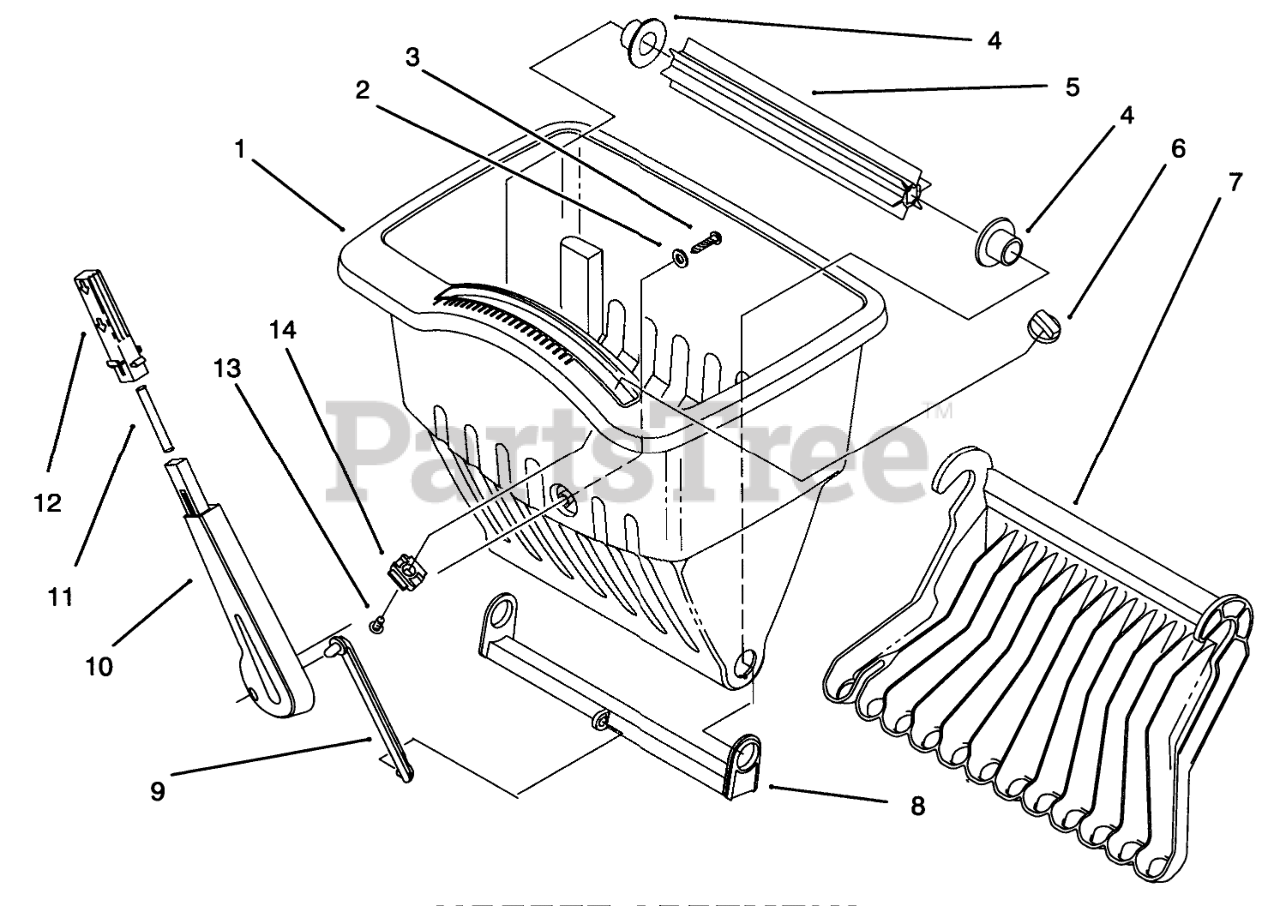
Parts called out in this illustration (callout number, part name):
1	Hopper Assembly
2	WASHER-PLAIN
3	SCREW-PPH
4	Bushing-Hopper
5	IMPELLER
6	KNOB, VFL/FFL
7	Chute
8	Adjuster-Flow
9	Rod-Connecting
10	Lever-Hopper
11	Spring-Compression
12	Handle-Lever
13	SCREW-CARR
14	Stop-Lever
